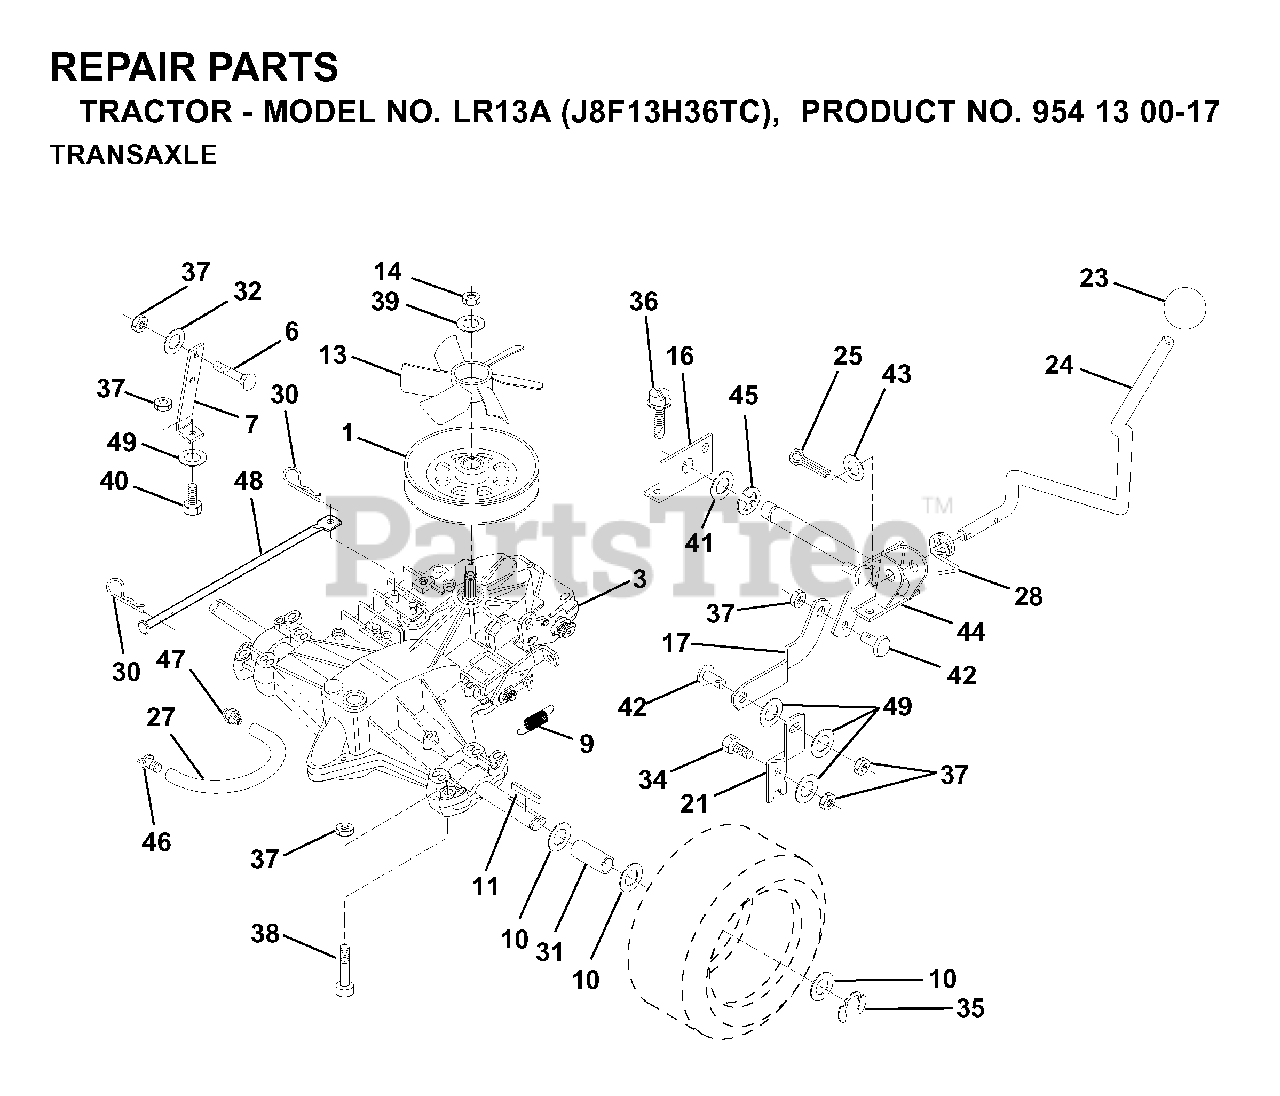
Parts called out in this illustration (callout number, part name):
3	TRANSAXLE HYDRO
6	BOLT
9	SPRING,BRAKE RETURN
11	SQUARE KEY
13	FAN.TRANSMISSION.HYDRO.6"
16	SUPPORT, SHIFT HANDLE
17	LINK, SHIFT
21	LEVER, SHIFT
23	KNOB.DUCKHEAD.1/2
24	ROD, SHIFTER
25	PIN COTTER
27	FUEL LINE
28	SPRING, TORSION
30	RETAINER M
31	SPACER SPLIT
32	WASHER
34	BOLT RB
35	E-RING LT
36	SCREW
37	NUT.71038.31-18.HEX.NYLOCK
40	BOLT
43	WASHER
44	PIVOT SHAFT
45	RETAINING RING LT
46	CAP, VENT ASSY
47	O-RING.ASM.70110
48	ACTUACTOR
49	WASHER M
